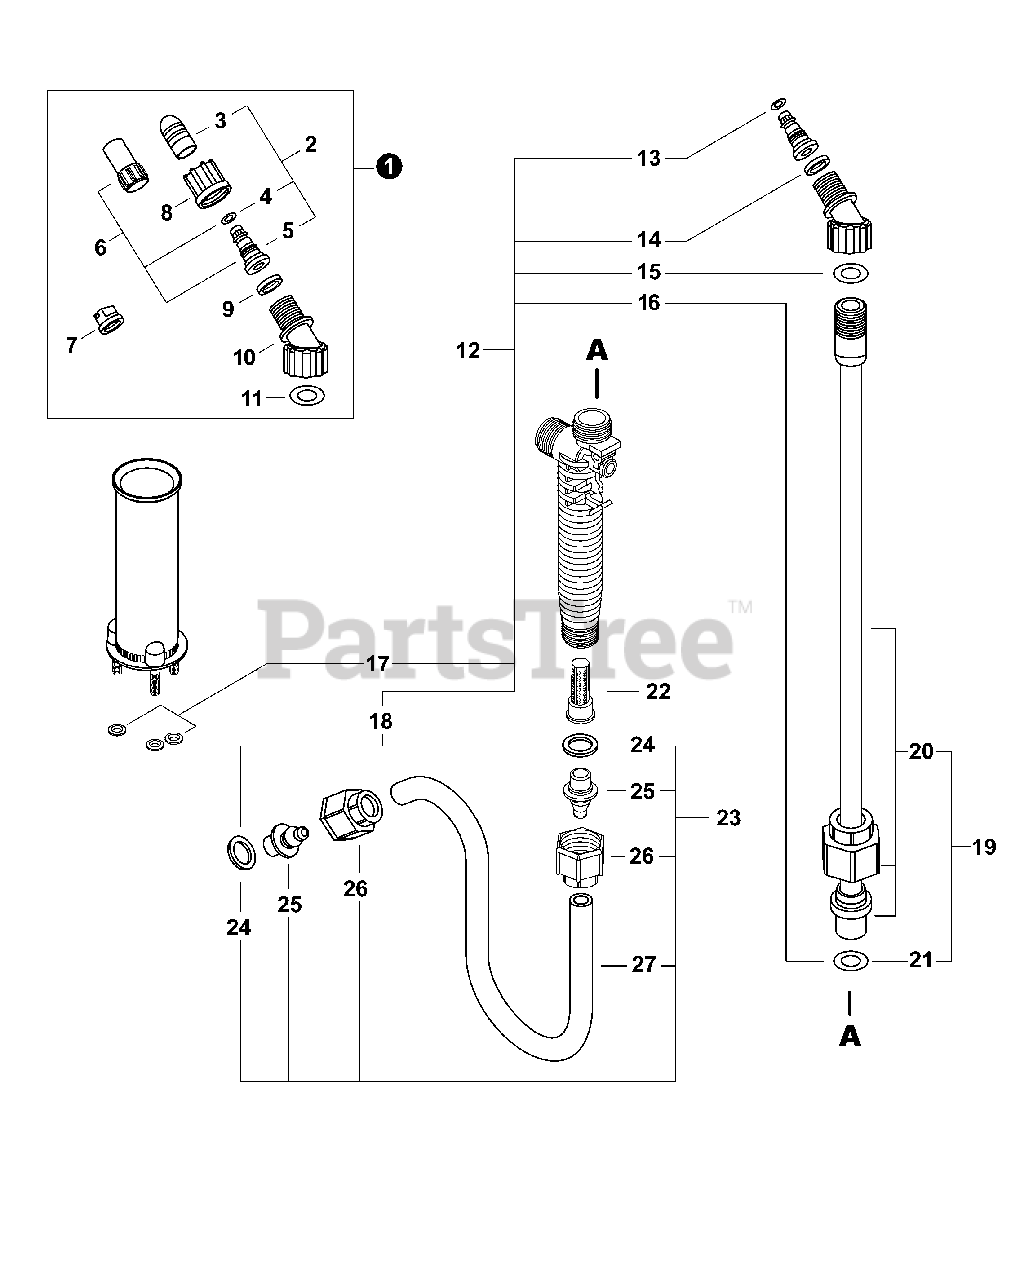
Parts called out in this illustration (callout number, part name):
1	NOZZLE KIT
2	NOZZLE KIT, BRASS
3	CAP, NOZZLE - BRASS
4	O-RING, NOZZLE
5	BODY, NOZZLE
6	NOZZLE KIT, PLASTIC
7	NOZZLE, FLAT FAN
8	NUT, NOZZLE
9	GASKET, NOZZLE
10	ELBOW, NOZZLE
11	O-RING, ELBOW
12	GASKET KIT, BPE
13	O-RING, NOZZLE
14	GASKET, NOZZLE
15	O-RING, ELBOW
17	GASKET, STUD
18	GASKET, ADAPTER
19	WAND ASSY, SPRAYER
20	WAND, SPRAYER
22	FILTER, SPRAY GUN
23	HOSE ASSY
24	GASKET, ADAPTER
25	ADAPTER, HOSE - BLACK
26	NUT, HOSE
